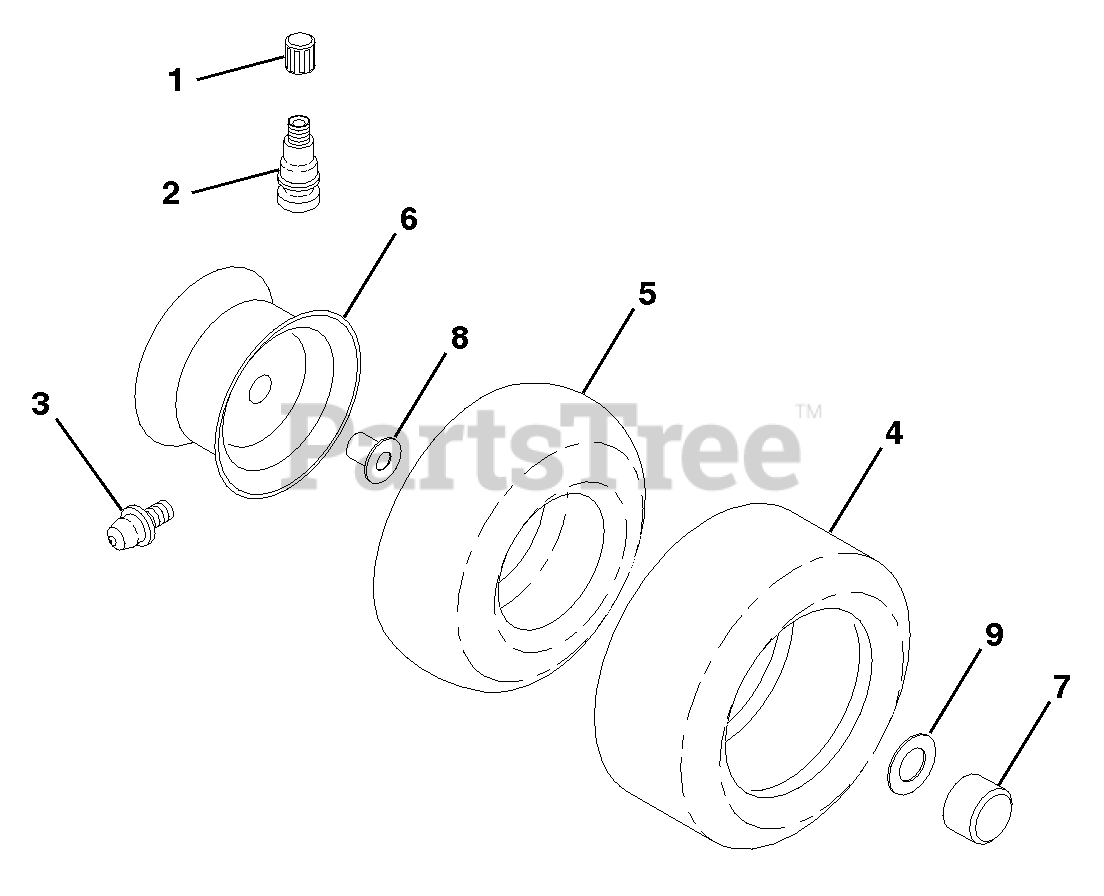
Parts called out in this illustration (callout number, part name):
1	Cap, Valve
2	Stem, Valve
3	Fitting, Grease
4	Tire, Front
4	Tire, Rear
5	Tube, Front
5	Tube, Rear
6	Rim, Front
8	Bearing Flange
9	Washer 25/32 x 1-5/8 x 16 Ga.
